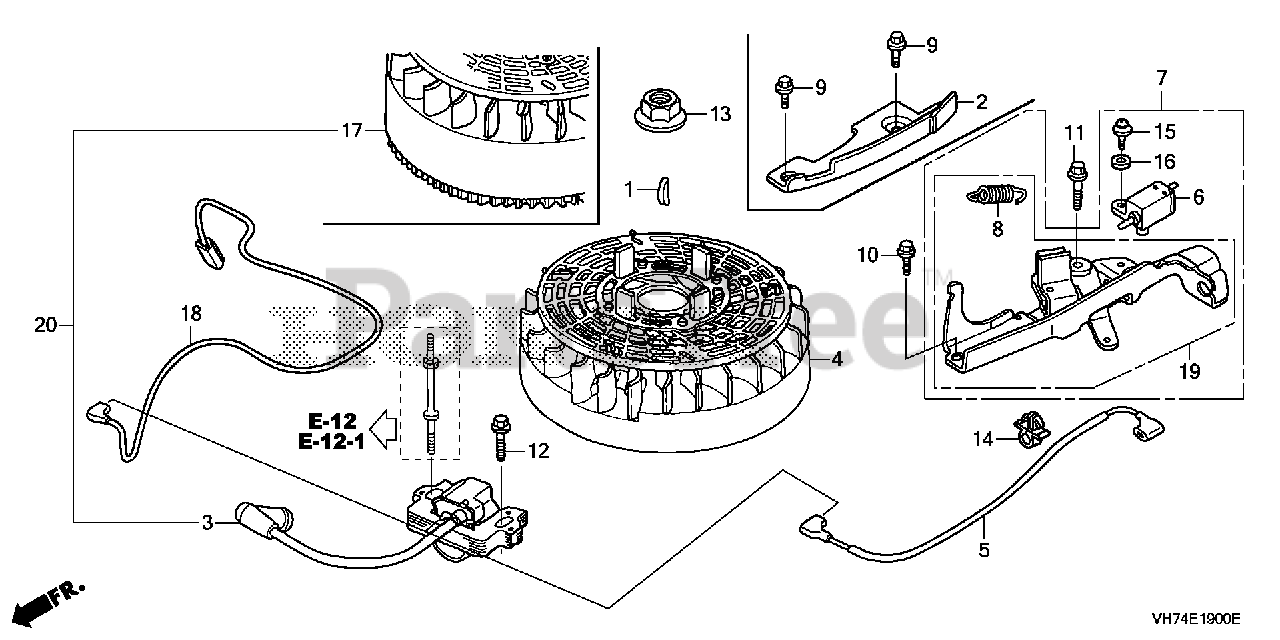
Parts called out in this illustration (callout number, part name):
1	KEY, SPECIAL WOODRUFF (25X18)
3	COIL ASSY., IGNITION (PHELON)
3	COIL ASSY., IGNITION (USE FOR F/W OF TEC) (TEC) Use up to Engine SN 3747197.
3	COIL ASSY., IGN
4	FLYWHEEL ASSY. (TEC) (USE FOR IGN. COIL OF TEC)
5	WIRE, STOP SWITCH
6	SWITCH ASSY., ENGINE STOP (Honda Code 5580683). (N.C)
7	BRAKE ASSY.
8	SPRING, BRAKE LEVER
10	BOLT, FLANGE (6X14)
11	BOLT, FLANGE (6X23)
12	BOLT, FLANGE (6X23)
13	NUT, FLANGE (14MM)
14	HOLDER, WIRE (FASTEX)
14	CLIP, CABLE (A)
15	SCREW-WASHER (4X12)
16	WASHER, PLAIN (4MM)
19	BRAKE ASSY.
